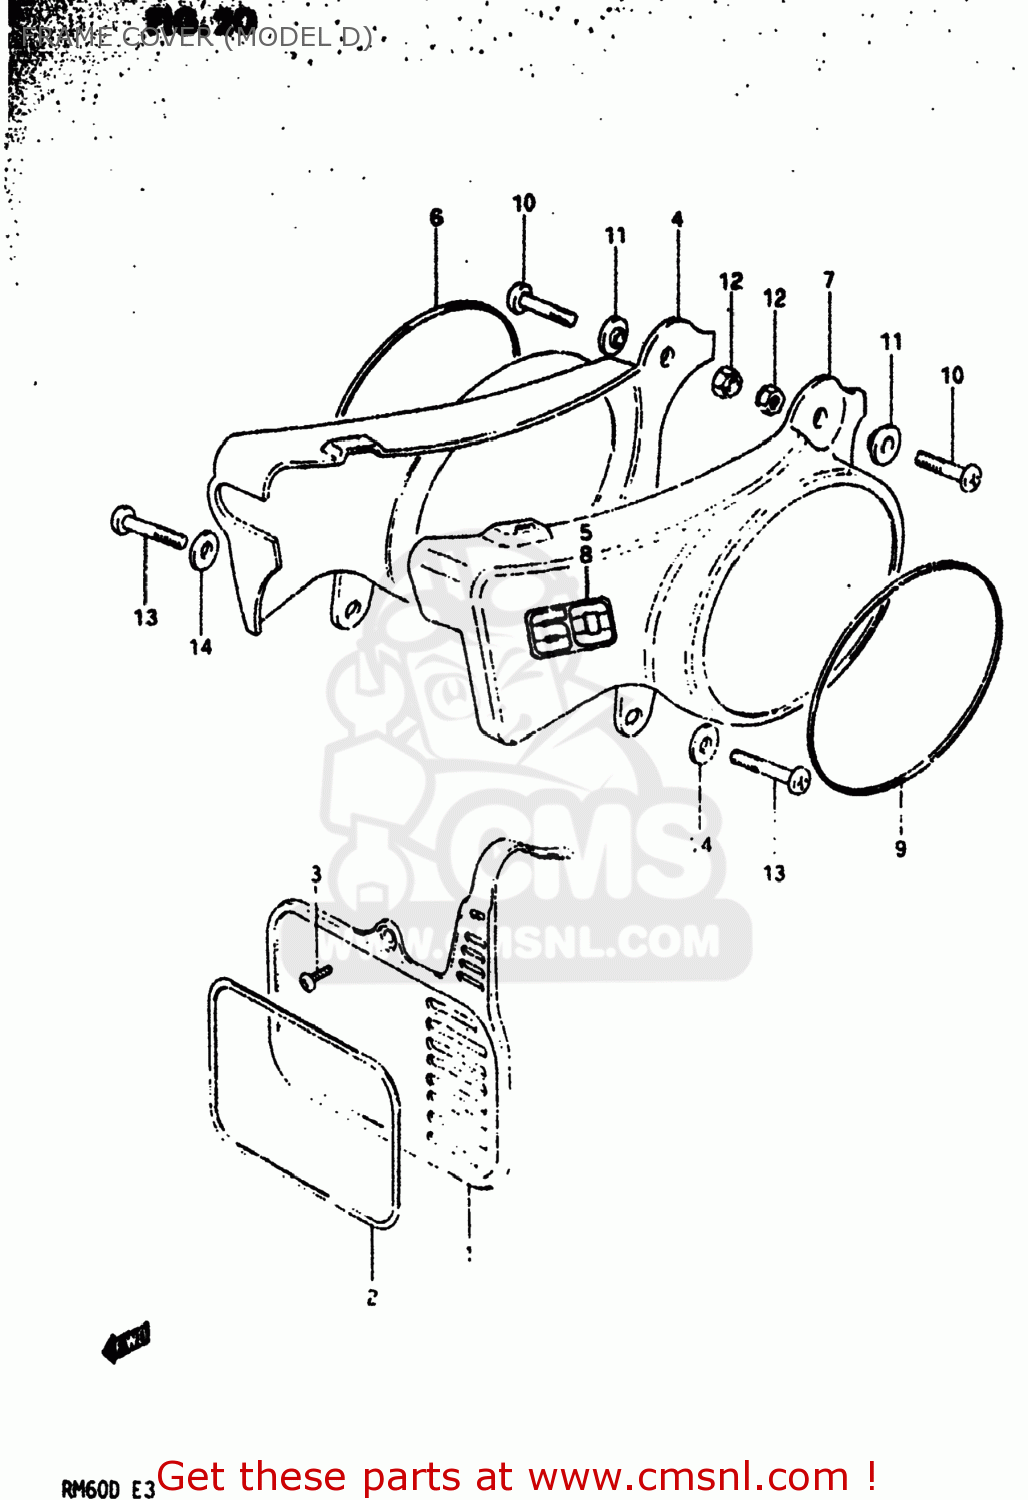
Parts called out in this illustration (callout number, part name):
1	PLATE,FR NUMBER
2	TAPE SET,FRONT NUMBER PLATE
3	SCREW
4	COVER,FRAME,RIGHT
5	EMBLEM
6	TAPE,FRAME COVER NUMBER PLATE
7	COVER,FRAME,LEFT
8	EMBLEM,FRAME COVER
9	LABEL,FRAME COVER
10	SCREW
11	WASHER
12	NUT
13	SCREW
14	WASHER
